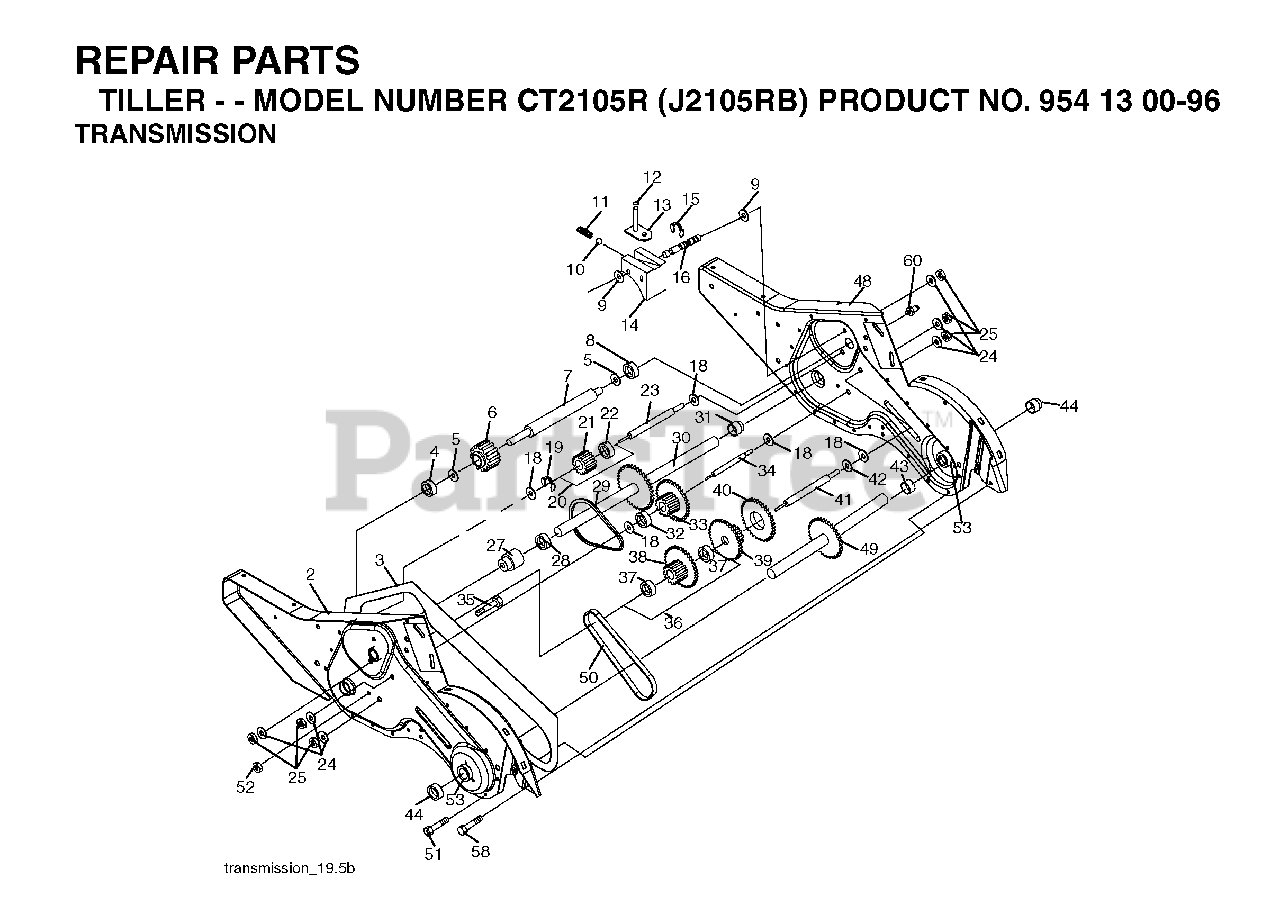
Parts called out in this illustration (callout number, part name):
1	TRANSMISSION ASM.
2	GEARCASE.ASM.CRT.LH.W/BEARING
3	GASKET
4	NEEDLE BRNG LT
5	THRUST WASHER
6	GEAR.PINION.INPUT
7	SHAFT.INPUT."D".TILLER
8	BEARING TI
9	WASHER, SEAL
10	STEEL BALL KIT
11	SPRING-SHIFT CRT
12	O-RING TI
13	SHIFTING ARM
14	SHIFT FORK TI
15	KLIP RING
16	SHAFT.SHIFTER.TILLER
19	KLIP RING
20	GEAR ASSY CRT
21	GEAR-REV IDLR CRT
22	NEEDLE BEARING TI
23	SHAFT CRT
24	LOCKWASHER
27	BEARING, SHAFT LH CRT
29	CHAIN CRT
30	GROUND SHAFT ASS'Y
31	BEARING, SHAFT RH CRT
32	SPACER TI
33	SPRCKT 8 GEAR CRT
34	SHAFT.SECONDARY.REDUCTION.CRT
35	SCRW WHIZ LOK CRT
36	SPROCKET ASS'Y W/BRG
37	BEARING
38	SPROCKET, TINE
39	GEAR TI
41	SHAFT.REDUCTION.TILLER
42	BRNG RACE T
43	SPACER TI
44	SEAL ASM, OIL
48	GEARCASE.ASM.CRT.RH.W/BEARING
49	TINE SHAFT
50	CHAIN.TILLER
51	SCREW
53	BEARING KIT
58	BOLT SHOULDER 1/4-20 UNC X.875
60	FITTING.GREASE.TAPERED
